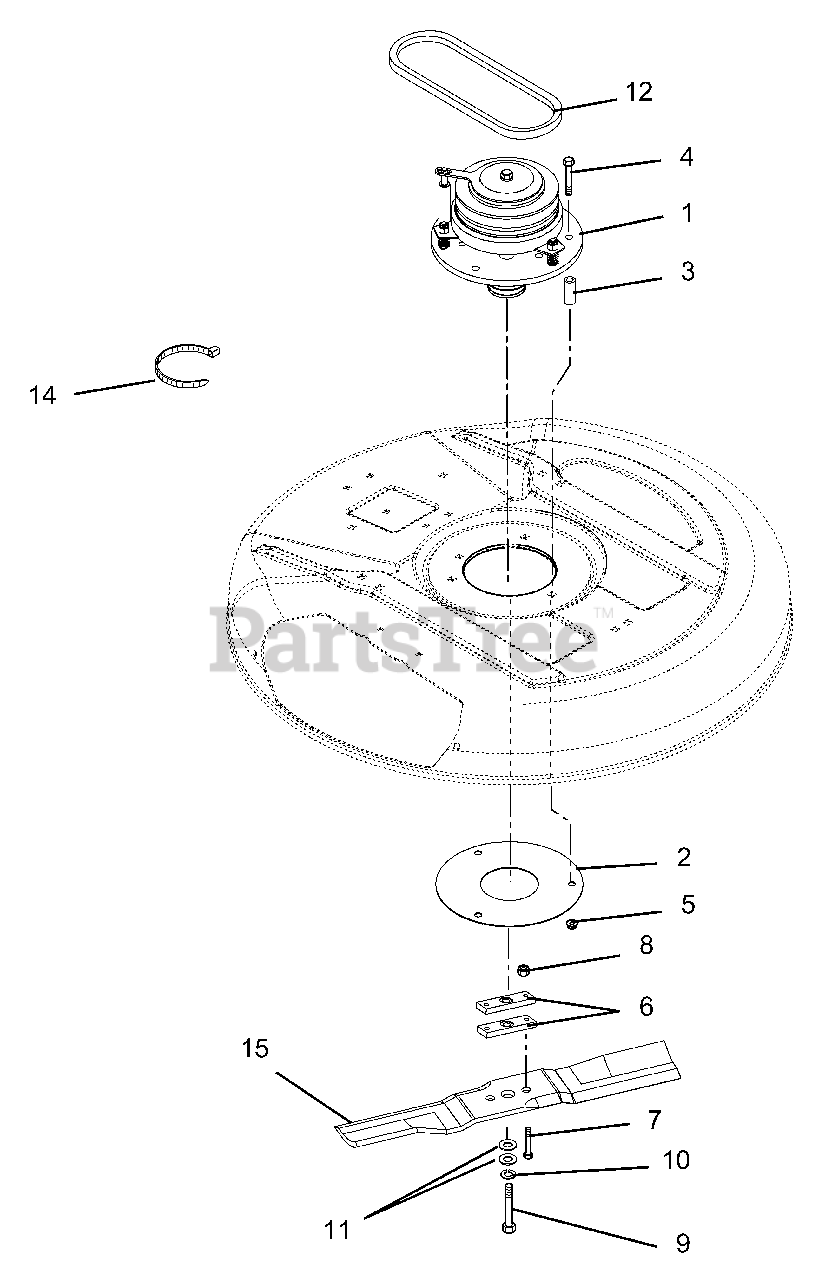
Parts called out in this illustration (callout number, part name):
1	Clutch/Spindle Assembly (28-inch mower decks)
2	Clutch Shield
3	Spacer .380 x .625 x 1.500
4	Bolt, Hex .38-16 x 2.75 Grade 5
5	Nut, Locking-Top-Flange .38-16
6	Spacer, 28/32 Blade
7	Bolt, Hex .38-24 x 2.00 Grade 8
8	Nut, Locking, Nylon .375-24 With Insert
9	Bolt, Hex 5/8-18 x 2-.50 Grade 8
10	Washer, Locking .62 x .156 Regular
11	Washer, Flat-Steel .656 x 1.31 x .095
12	V-Belt A-Section 25.1 x .495 (28-inch mower decks)
12	V-Belt HA 64.25 x .531 (32-inch mower decks)
14	Cable Tie
15	Blade, 28-Inch Mower
15	Blade, 32-Inch Mower
